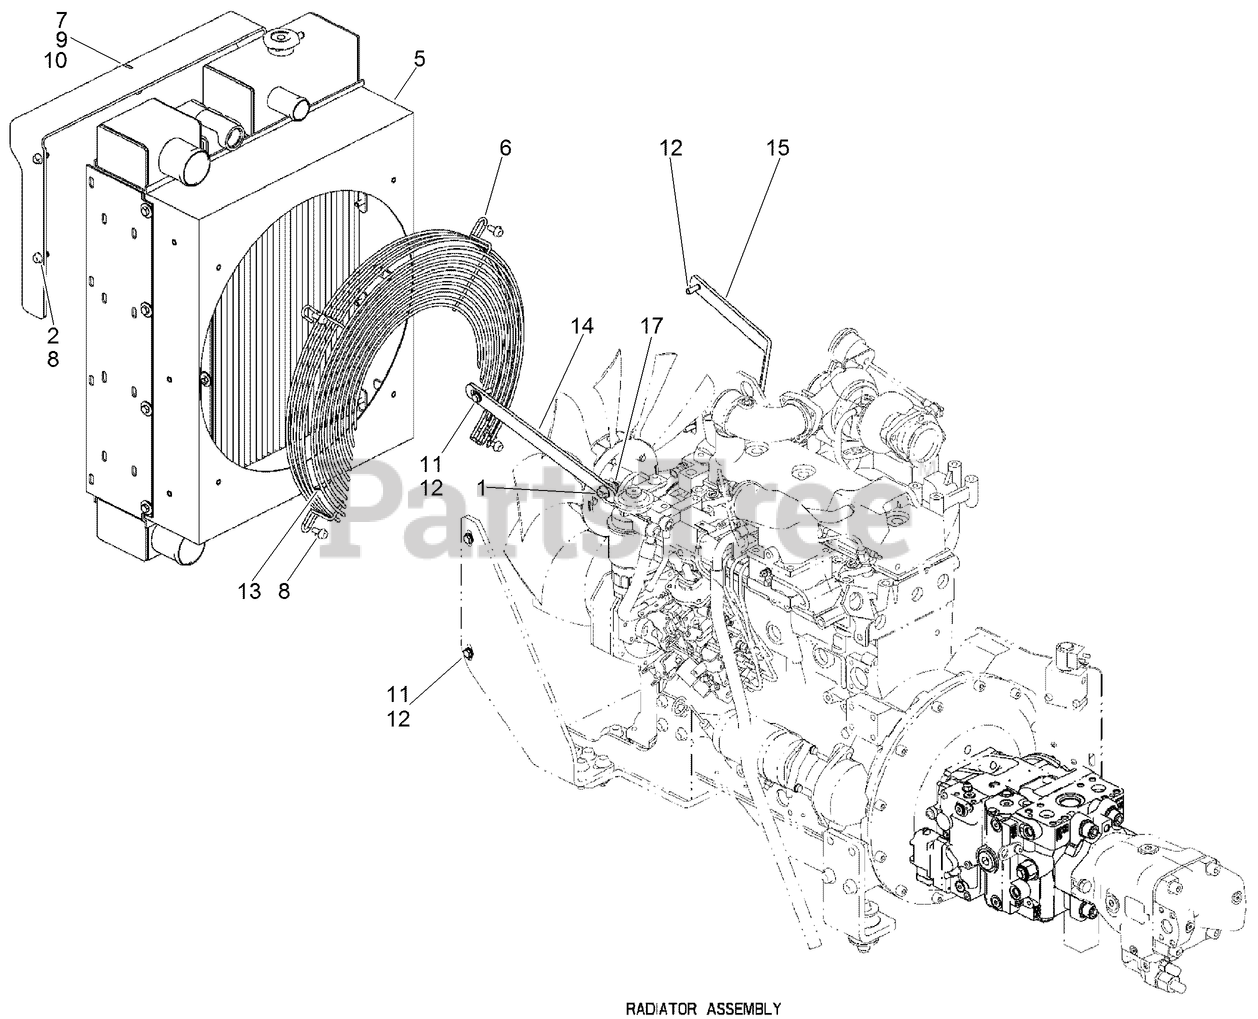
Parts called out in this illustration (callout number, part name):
1	SCREW-HH
2	NUT, METRIC FLANGE PREVAILING - M6 Zinc
5	RADIATOR - w/Charged Air
6	GUARD-Fan
7	ASSEMBLY - Shock Mount
8	SCREW, METRIC FLANGE w/BODY - M8 x 20
9	STUD-BALL
10	NUT - Prev Trq 5/16 GRB ZND Direct
11	WASHER-FLAT
12	BOLT-Hex, 5/16 NC x 1-1/4 inch
13	PLUG - Hdls Hex Skt Pipe 1/4 ZN
14	PLATE - Radiator Strap Mount
15	PLATE - Radiator Strap Mount
17	NUT-FLANGE, NYLOCK
